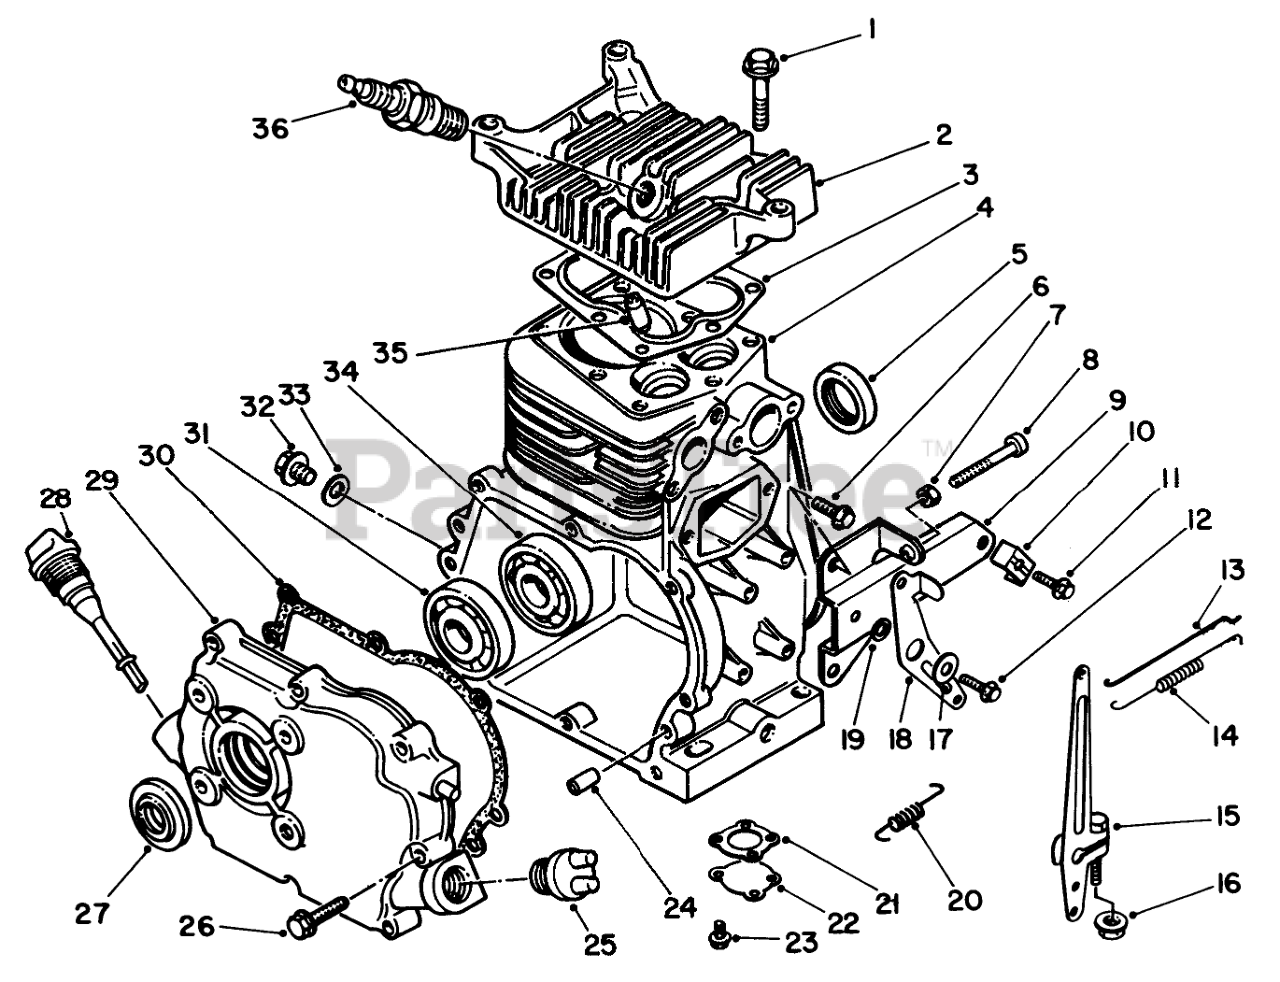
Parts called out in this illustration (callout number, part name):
2	Cylinder Head
3	GASKET
4	Cylinder
5	Oil Seal
8	Screw-Round Phillips Hd.
9	Bracket-Governor Control
10	CLAMP-CABLE
13	Rod-Carburetor
14	SPRING
15	Lever-Control
17	WASHER
18	Lever-Governor Control
19	Washer
20	Spring
21	GASKET
22	Cover-Level Sensor
27	Oil Seal
28	Gauge-Oil Level
29	Cover-Crankcase Side
30	Gasket-Crankcase
31	Bearing
32	Drain Plug
33	GASKET
34	Bearing
35	Guide Valve
36	SPARK PLUG
